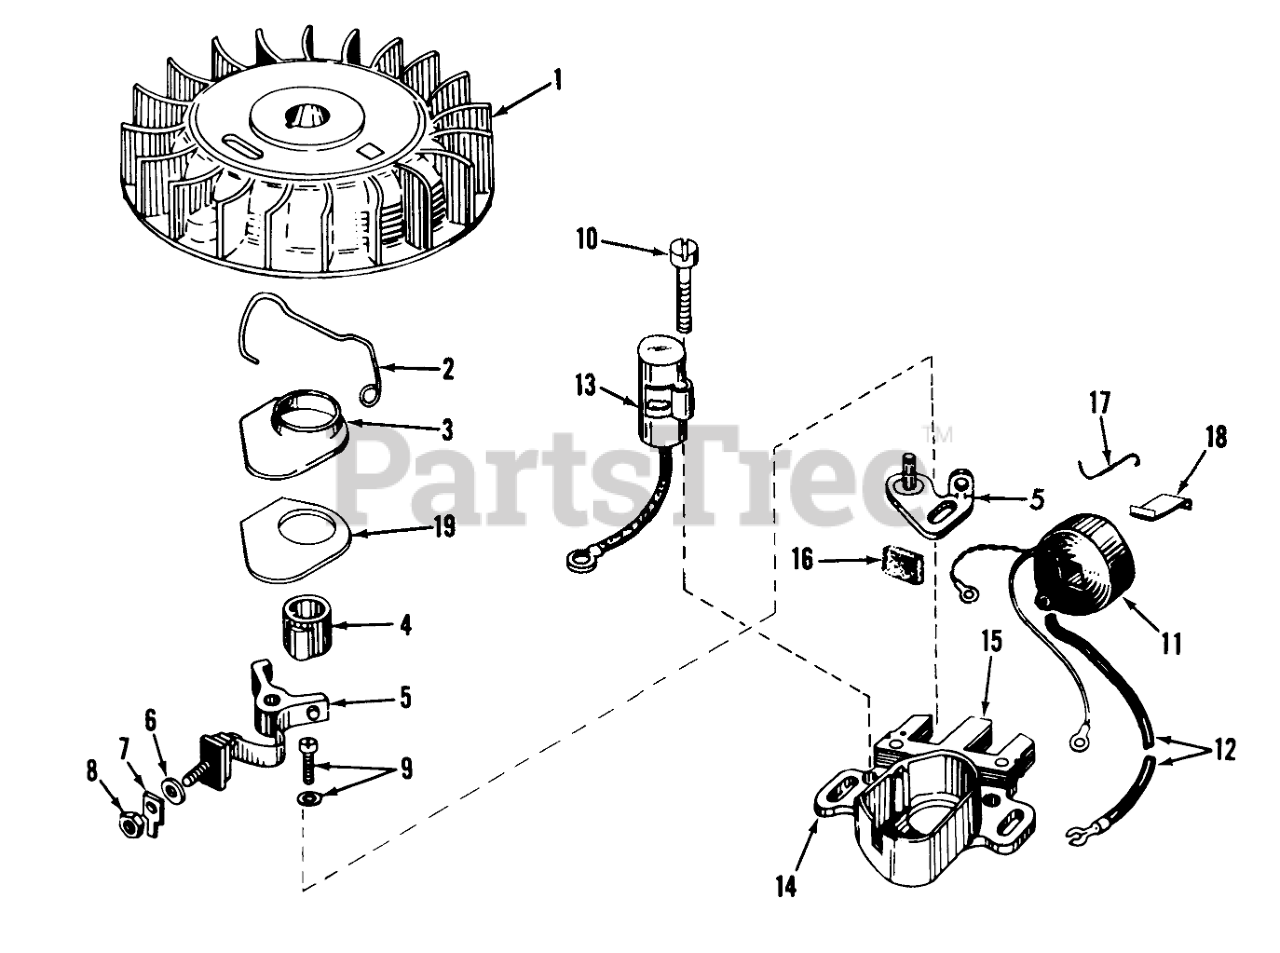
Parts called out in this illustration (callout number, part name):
1	Flywheel
2	Spring Breaker Box
3	Cover, Dust
4	Cam-Breaker
5	Breaker Assy.
7	Terminal
9	Breaker Screw
10	Condenser Screw
11	Coil Assy. (Incl. Ref. Nos. 12, 13 & 18)
12	Wire, Lead
13	Condenser
14	Core & Plate
15	Stator Assy. (Incl. Nos. 2, 3, 5 thru 14 & 16 thru 19)
16	Felt,Cam Wiper
17	Clip, Coil
18	Spring Coil Wedge
19	Gasket Dust
